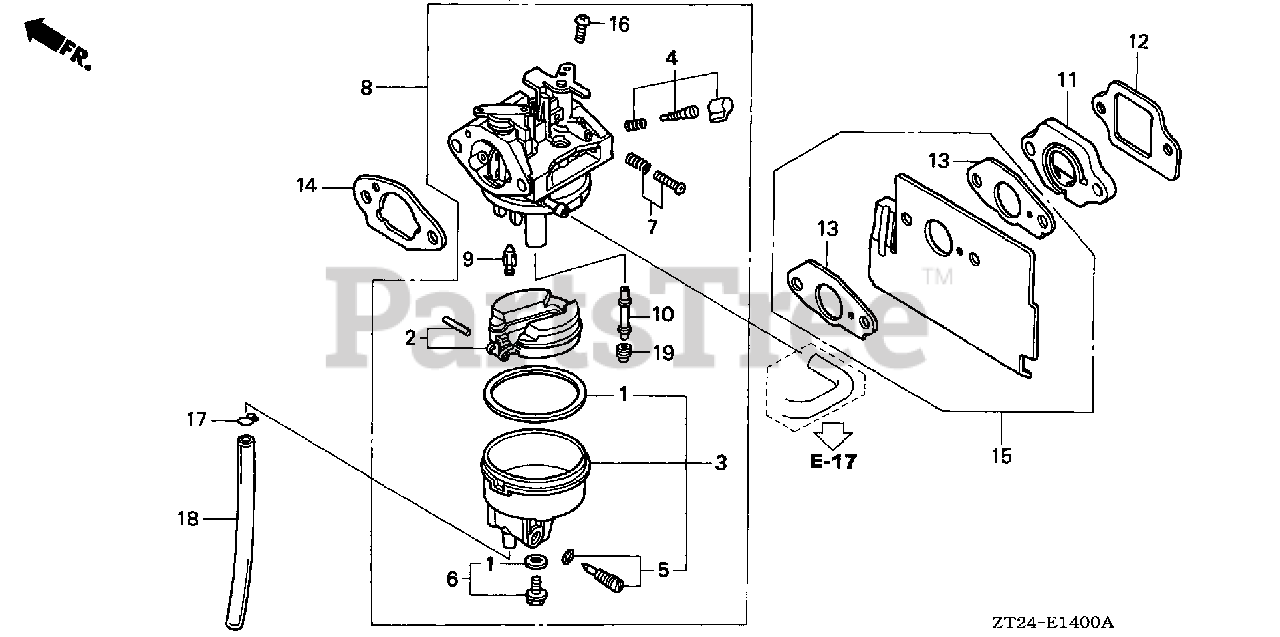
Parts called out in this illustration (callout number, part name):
1	GASKET SET
3	CHAMBER SET, FLOAT
5	SCREW SET, DRAIN
6	SCREW SET
7	SCREW SET (THROTTLE STOP)
8	CARBURETOR ASSY. (BB61B C)
8	CARBURETOR ASSY. (BB61B D)
8	CARBURETOR ASSY. (BB61J A)
9	VALVE, FLOAT (CARBURETOR NO.)
10	NOZZLE, MAIN
11	INSULATOR, CARBURETOR
12	GASKET, INSULATOR
13	GASKET, CARBURETOR
14	GASKET, CARBURETOR
15	GUIDE, AIR
16	SCREW, PAN (5X6)
17	CLIP, TUBE (B6.5)
18	BULK HOSE, VINYL (4X7X8000) (4X7X150)
19	JET, MAIN (#60)
19	JET, MAIN (#62)
19	JET, MAIN (#65)
